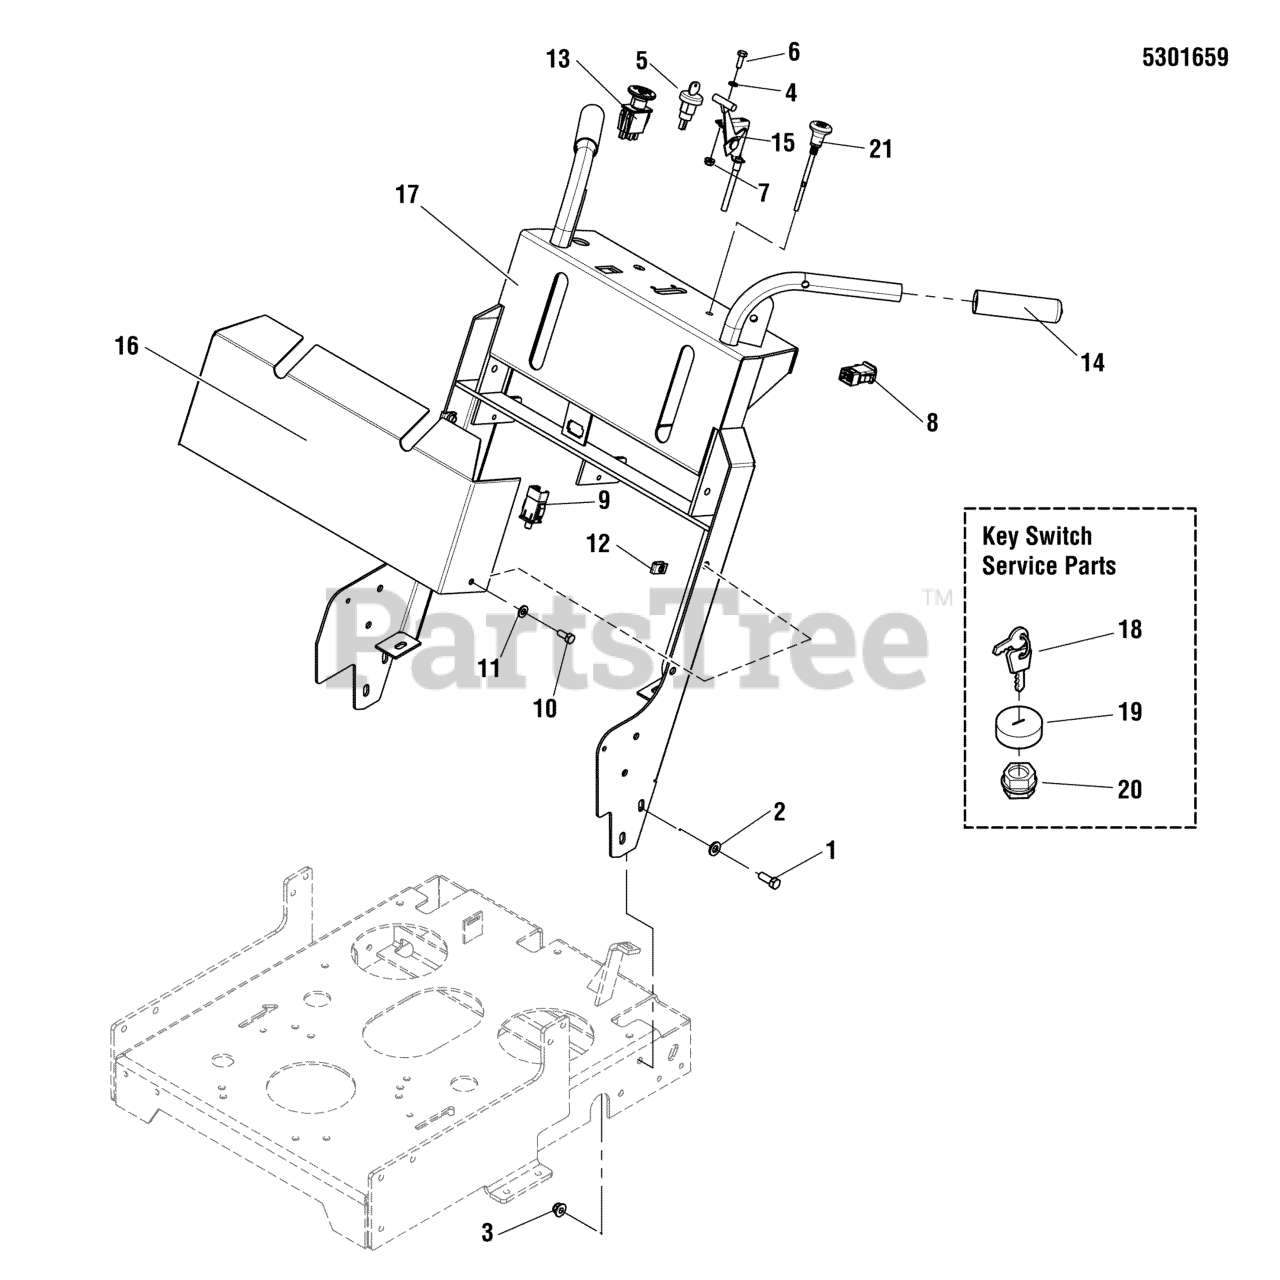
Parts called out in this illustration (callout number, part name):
1	BOLT, 3/8-16 X 1" GD5 CZ
2	WASHER, 3/8 GD.9 FLAT
3	NUT, 3/8-16 HEX NYLOCK FLANGE
4	WASHER, 1/4 SAE
5	SWITCH, IGNITION, 2 POST
6	BOLT, 1/4-20 X 3/4 GD5 YZ
7	NUT, 1/4-20 HEX NYLOCK FLANGE
8	SWITCH, PLUNGER, NO/NC SNAP-IN, LOW PROFILE
9	SWITCH, PLUNGER, NC, SINGLE POLE SNAP-IN
10	BOLT, 5/16-18 X 3/4 GD5
11	WASHER, 5/16" SAE
12	BODY CLIP, 5/16-18-7GA MATERIAL
13	SWITCH, BLADE ENGAGEMENT
14	GRIP, FOAM, .940" X 4.62" X .187"
15	CABLE, THROTTLE, 54"
16	HANDLE BAR COVER W/ DECALS, HD1648
18	KEY, IGNITION MOLDED SET
19	COVER, PLASTIC, SNAP ON
20	PLASTIC NUT
21	CABLE, CHOKE CONTROL, 56"
